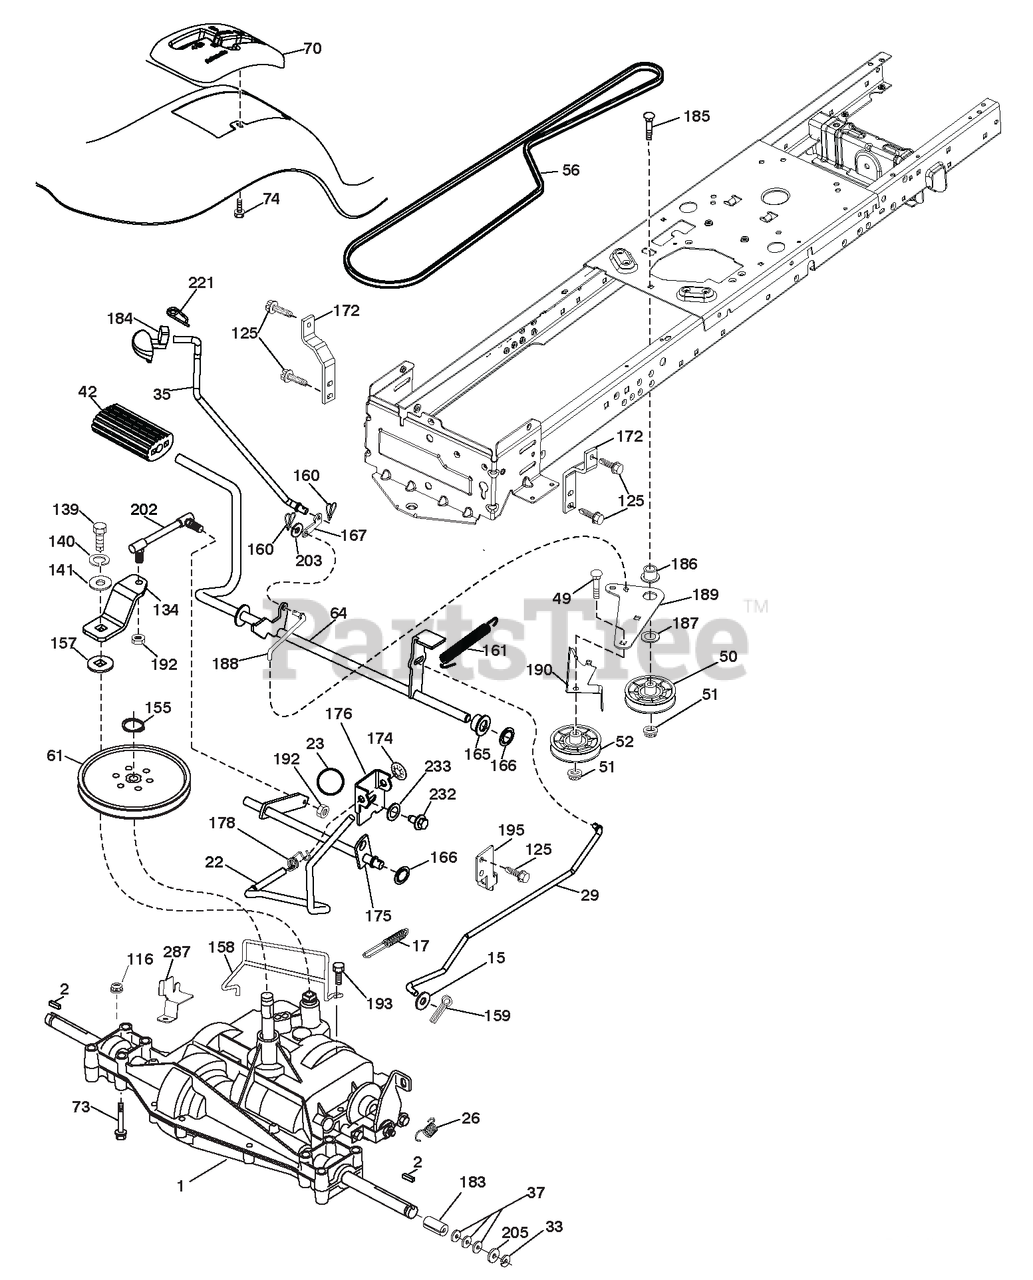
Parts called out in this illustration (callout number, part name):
2	KEY.SQUARE.2.0 X .1845/.1865
15	WASHER.13/32 X 13/16 X 16 GA.
17	SPRING.BRAKE.PEERLESS/D6800.TX
22	ROD.SHIFT.FENDER.TLT.2006
26	SPRING.BRAKE.RTN.GR DR.TEX.006
29	ROD.BRAKE.PEERLESS/D6800
33	E-RING.#5133-75
35	ROD.BRAKE.PARKING.LT.TEX
37	WASHER.25/32 X 1 1/4 X 16 GA.
42	COVER PEDAL BLK ROUND
49	BOLT.RDHD.3/8-16UNCX1-3/4.GR5
50	IDLER.FLAT.910"OFFSET
51	Nut, Hex, Flangelock 3/8-16
52	IDLER.V-GROOVE.910"OFFSET
56	V-Belt Ground Drive
64	SHAFT ASM.PEDAL.BRAKE CONTROL
70	CONSOLE SHIFT
73	BOLT 5/16-18 X 2 1/2 G.5
74	SCREW.HEX.WSH.HI-LO.1/4X1/2UNC
116	Nut, Lock Hex Flange 5/16-18 u
125	SCREW.5/16-18X3/4.SMGML.TAP/BL
134	ARM.SHIFT.T/A.PMST.18"LT.TEX
139	BOLT.1/4-28 UNF.GR8.W/PATCH
140	Washer, Lock 1/4
141	WASHER.9/32 X 3/4 X 10 GA.
155	Ring, Retainer
157	WASHER.PLATE.SHF..388 SQ.HOLE
158	KEEPER.T/A.PMS/D4360/D680.1820
159	PIN.COTTER.1/8 X 3/4.CAD.
160	RETAINER.CLIP(M).DIA.290
161	SPRING.RETURN.CLUTCH.6.75
165	BUSHING.SHAFT.BRAKE.HAND CONTR
166	NUT PUSH .625
167	LATCH.BRAKE.PARKING
172	STRAP.TRQ.LH.GEAR DRIVE.LT.TEX
174	NUT.PUSH..500
175	SHAFT ASM.SHIFT.GR DRV.18"LTEX
176	ARM.CLEVIS.ROD.SHIFT
178	SPRING.SHIFT.GT.2006
183	SPACER.AXLE.HYDRO/PEERLES
184	HANDLE.PARKING.BRAKE
185	BOLT.RDHD.3/8-16UNC X2-3/4 GR5
186	SPACER.RETAINER
187	WASHER.13/32 X 2 X 10 GA.
188	LINK.CLUTCH.GROUND DRIVE
189	BELLCRANK.GROUNDRIVE.NSTG/NSTL
190	KEEPER.BELLCRANK.DRIVE.GROUND
192	NUT.LOCK.CENTER.1/4-28 FNTHD.
193	SCREW.5/16-18X3/4.SMGML.TAP/R
195	BRACKET.ROD.BRK.PEERLESS/D6800
202	LINK.SHIFT PMST.18HP
203	Washer 11/32 x 11/16 x 16 Ga.
205	WASHER.25/32 X 1-5/8 X 16GA.
221	RETAINER.SPRING.CLIP.HANDLE
232	BOLT.FIN HEX.7/16-14X1 GR5
233	WASHER.SERRATED
287	KEEPER.PULLEY
